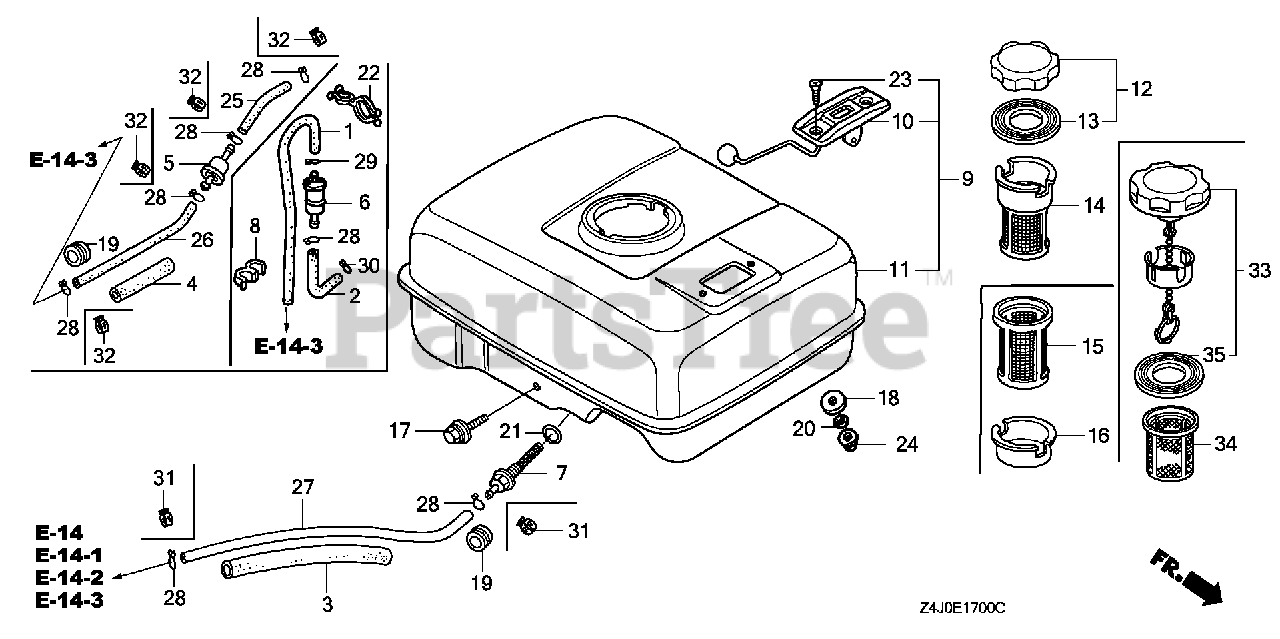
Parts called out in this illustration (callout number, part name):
3	RUBBER, SUPPORTER (107MM)
7	JOINT, FUEL TANK
11	TANK, FUEL *NH31* (MCKINLEY WHITE)
12	CAP, FUEL FILLER (CHROME PLATED)
13	GASKET, FUEL FILLER CAP (39X62X3) (TOUYOUSYA)
17	BOLT, FLANGE (6X29)
21	O-RING (13.5X1.5) (ARAI)
21	O-RING (14MM) (NOK)
24	NUT, FLANGE (6MM)
27	TUBE, FUEL (4.5X140) (FKM)
27	BULK HOSE, FUEL (4.5X3000) (4.5X140)
28	CLIP, TUBE (B8)
31	CLAMP, TUBE (D8)
33	CAP, FUEL FILLER (CHROME PLATED)
33	CAP, FUEL FILLER
35	GASKET, FUEL FILLER CAP (39X62X3) (RADICON)
